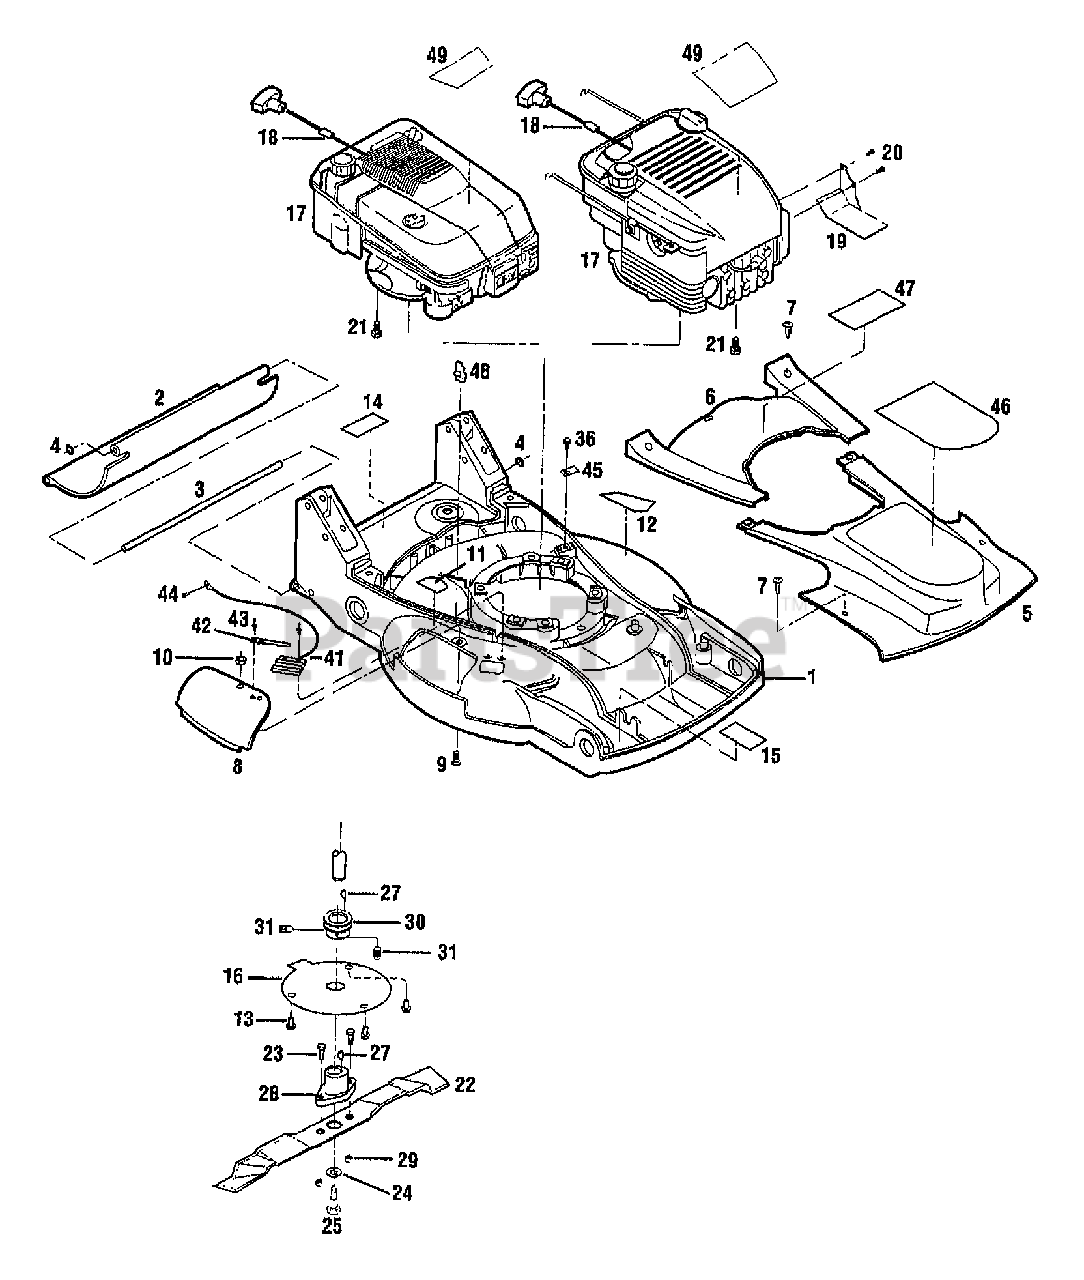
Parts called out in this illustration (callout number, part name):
1	MOWER DECK W/DECALS (INCL. 2-4,9,11,12,14, 15,41 & 43)
2	FLAP-SAFETY WITH NOTCH
4	RING-RET. "E".312 ID
5	COVER W/DECAL FRONT (INCL. 46)
6	COVER-REAR W/DECAL (INCL. 47)
7	SCREW- M12-24X.63 THREAD FORMING
8	DOOR-DISCHARGE W/TAB (INCL. 42 & 43)
9	SCR-SPECIAL 5/16-24X.75
10	NUT-HT/LK 5/16-24
11	DECAL-DANGER USE GUARD (34320,34320C,34321, 34321C,34322,34322C,34323,34323C)
11	DECAL-DANGER GUARD (34044,34045,34046)
12	DECAL-OPEI CAUTION
13	SCR-HWH 1/4-20 X .5 STH (34321,34321C,34322, 34322C,34323,34323C)
14	DECAL-WARNING THROWN OBJECT
14	DECAL-THROWN OBJECTS (34044,34045,34046)
15	DECAL-CAUTION PINCH POINT (34321,34321C, 34322,34322C,34323,34323C)
15	DECAL-CAUTION PINCH POINT (34045,34046)
16	PLATE-SHIELD GRASS
17	ENGINE, BRIGGS & STRATTON 4HP (ACTU. 5HP) #XTE 12F802-1174-01 (34320,34321)
17	ENGINE, BRIGGS & STRATTON 5HP #12F802-0833- 01 (34320C,34321C)
17	ENGINE, BRIGGS & STRATTON 5HP #XTE 12F802- 1174-01 (34322)
17	ENGINE, BRIGGS & STRATTON 5HP 12F802-0833- 01 (34322C)
17	ENGINE, BRIGGS & STRATTON 5HP 12F807-1174- 01 (34323)
17	ENGINE, BRIGGS & STRATTON 5HP 12F802-0835- 01 ELEC. START (34323C)
18	STOP-STARTER ROPE
19	SHIELD-HEAT PNT
20	SCR-SELF TAP
21	SCR-HH 3/8-16X1.25 THDFRM
22	KIT-BLADE 21" MULCH MOWER (INCL. 23 & 29)
22	BLADE-MULCHER 21" (BLADE ONLY)
23	SCR-HH 3/8-16X1.0 G5
24	WASHER-LK .5
25	SCR-SHLDR 3/8-24X1.63
26	THIS REF. NO. NOT USED
27	KEY-WOODRUFF
28	COUPLING-BLADE
29	NUT-LOCK 3/8-16
30	SHEAVE-ENGINE {NOT 34320,34320C,34044}
31	SCR-SQHD 1/4-20X1/2 GR5 {NOT 34320,34320C, 34044}
32	THIS REF. NO. NOT USED
33	THIS REF. NO. NOT USED
34	THIS REF. NO. NOT USED
35	THIS REF. NO. NOT USED
36	THIS REF. NO. NOT USED
37	THIS REF. NO. NOT USED
38	THIS REF. NO. NOT USED
39	THIS REF. NO. NOT USED
40	THIS REF. NO. NOT USED
41	SWITCH-IGNITION GROUND
42	TAB-SWITCH
43	RIVET-POPOP
44	SCR-HH 10-24X.25 THRD FRM
45	THIS REF. NO. NOT USED
46	DECAL-COVER
47	DECAL-WARNING SAFETY LIST
47	DECAL-WARNING REAR COVER {34044,34045,34046}
48	CLIP-SPECIAL {NOT 34320,34320C,34044}
49	DECAL-ENGINE 4HP {34320,34320C}
49	DECAL-ENGINE (34321,34321C,34322,34322C, 34323,34323C,34044))
49	DECAL-LOGO 6HP T/B (34045,34046)
